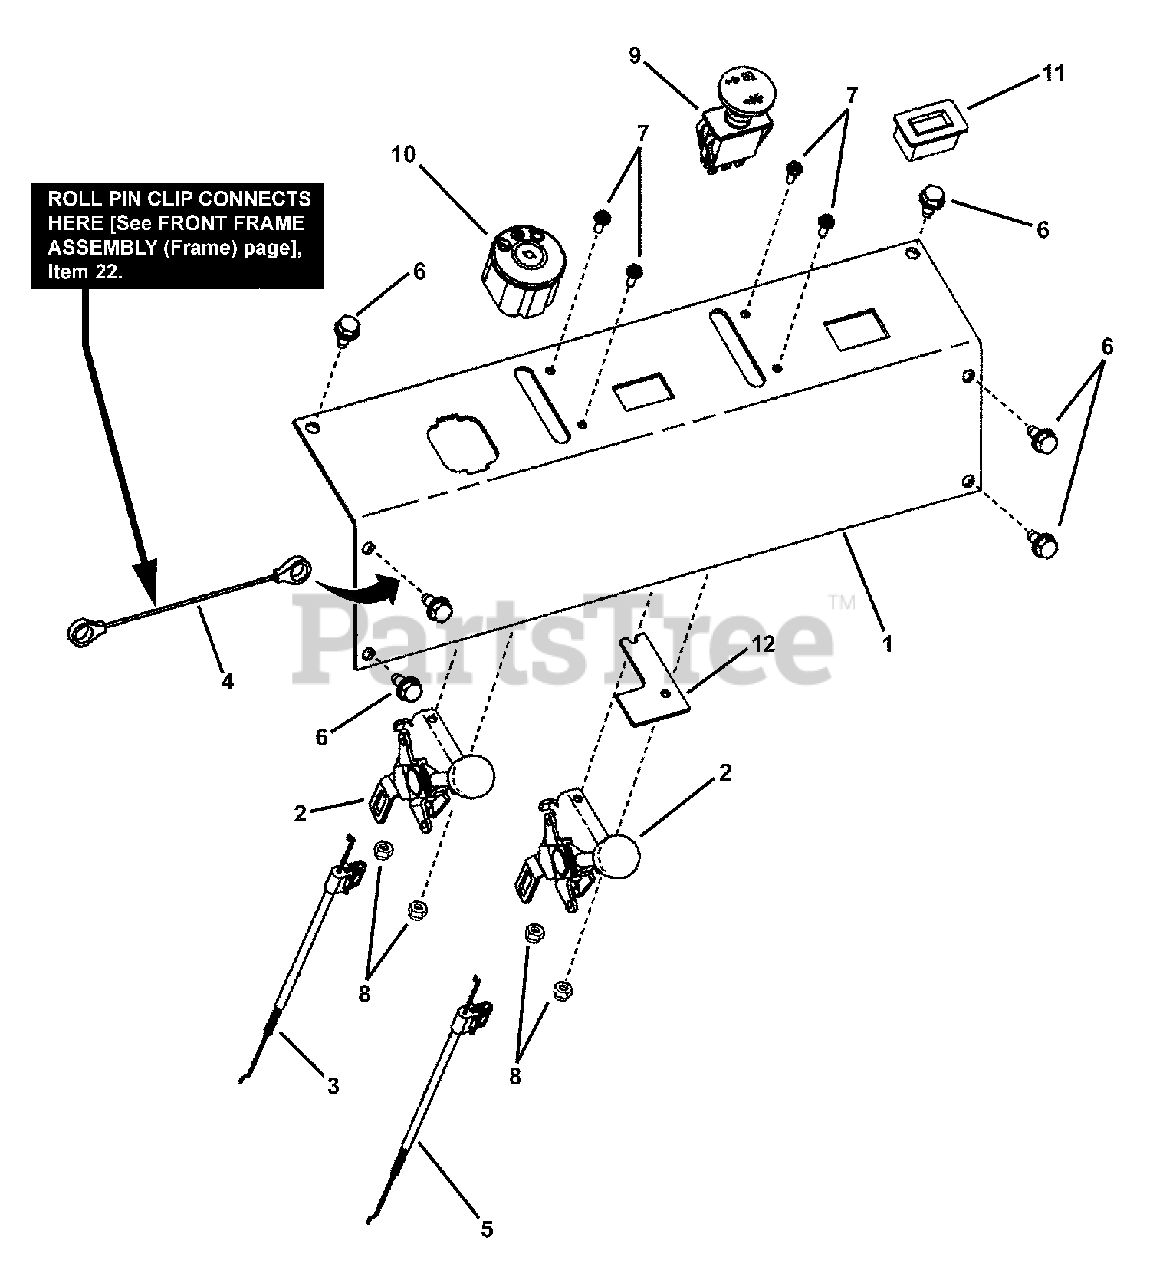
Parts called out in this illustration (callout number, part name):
1	CONTROL PANEL
2	CONTROL LEVER, Throttle/Choke
3	CONTROL CABLE, Throttle
4	STRAP, Tether
5	CONTROL CABLE, Choke
6	SCREW, 5/16-18 x 5/8" Hex Washer Self-Tap
7	SCREW, #10-32 x 5/8" Hex Washer Self-Tap
8	NUT, #10-32 Nyloc
9	SWITCH, PTO, Yellow
10	SWITCH, Ignition
11	HOUR METER w/Flash Alerts
12	CHOKE PLATE, Kohler
